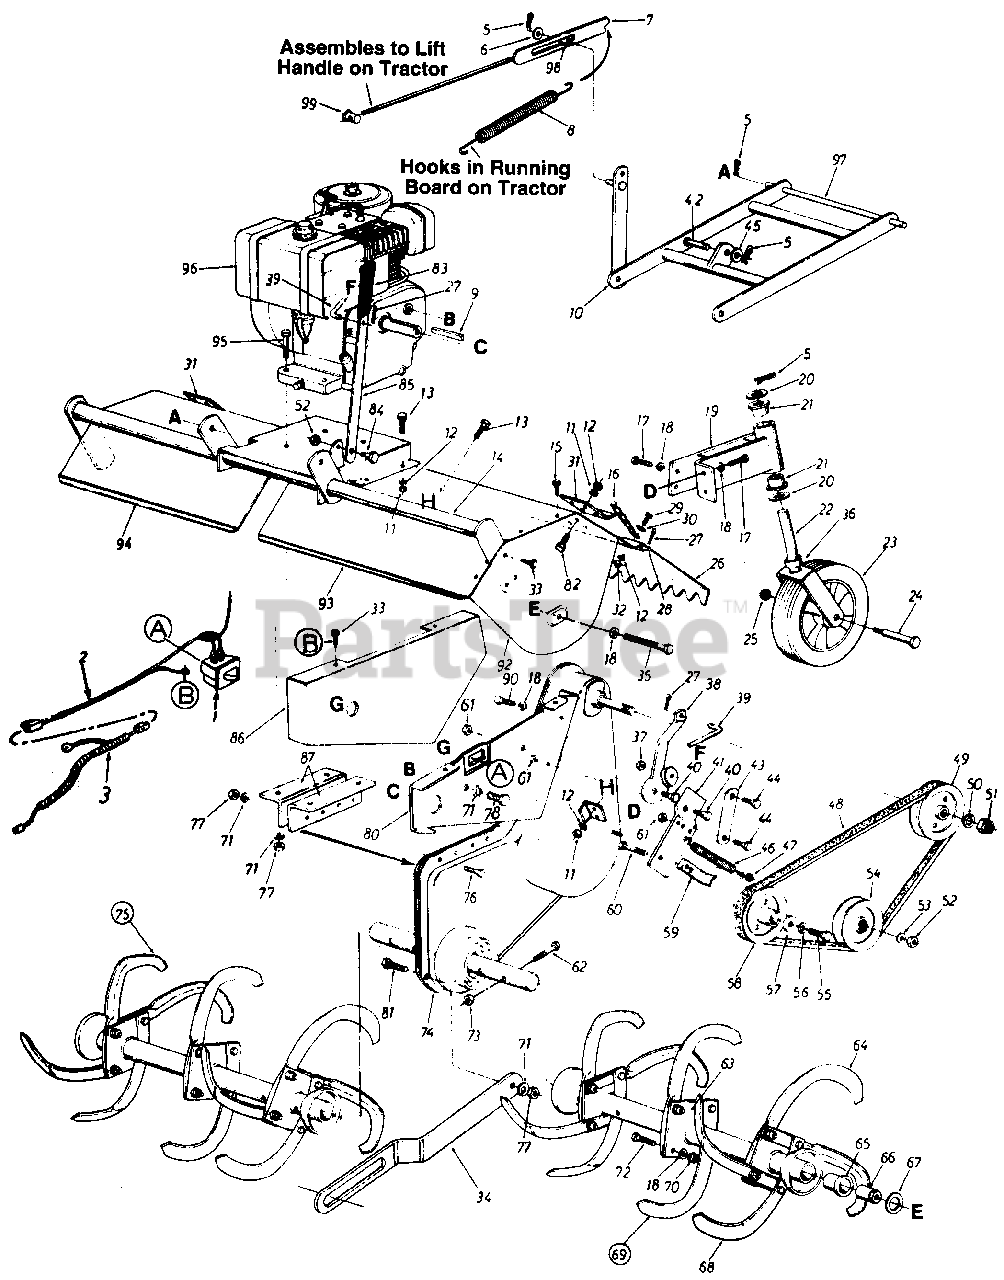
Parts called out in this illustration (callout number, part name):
1	Safety Switch
2	Wire Harness
3	Adapter Harness
5	Internal Cotter Pin
6	Fl-Wash. 1/2" I.D. x .93" O.D,
9	Sq. Key 1/4" x 1/4" x 2.00" Lg.
12	L-Wash. 1/4" I.D.
13	Hex Bolt 1/4-28 x .62" Lg.
16	#2 Dog Chain x 20" Lg.
17	Hex Wash. Hd. Self-Tap Scr. 3/8-24 x .75" Lg.
18	L-Wash. 3/8" I.D.
21	Flange Bearing 3/4" I.D. x 1.00" O.D.
24	Shoulder Bolt .623" I.D. x 3.62" Lg.
25	Hex Cent. L-Nut 7/16-14 Thd.
28	L.H. Flap Rod
29	Hex Bolt 1/4-20 x .62" Lg.
30	Fl-Wash. 1/4" I.D.
33	Hex Wash. Hd. Self-Tap Scr. 1/4" x .62" Lg.
36	Spacer .752" I.D. x 1.25" O.D.
37	Hex Cent. L-Nut 5/16-18 Thd.
40	Shoulder Bolt 7/16" Dia. x 1.75"
45	Fl-Wash..50" I.D. x 1.0" O.D. x .06
46	Extension Spring .62" O.D. x 6.12" Lg.
47	Hex Crown Nut 3/8-24 Thd.
48	"V"-Belt (Kevlar)
49	1/2" "V"-Pulley 4.75" O.D. x .625" Bore
50	L-Wash. 5/8" I.D.
51	Hex Ins. L-Nut 5/18-16 Thd.
52	Hex Cent. L-Nut 3/8-16 Thd.
53	Fl-Wash. 3/8" I.D.
54	Idler Pulley 4.0" O.D.
55	Hex Bolt
56	L-Wash. 7/16" I.D.
57	Fl-Wash. 7/16" I.D. x 1.38"
58	1/2" "V"-Pulley .475" O.D. x 1.00" Bore
61	Hex Cent. L-Nut 5/16-18 Thd.
62	Hex Bolt 7/16-14 x 2.00" Lg.
66	Spacer
67	Thrust Wash. 1/2" I.D. x 1.55"
71	L-Wash. 5/16" I.D.
72	Hex Bolt 3/8-24 x 1.5" Lg.
73	Hex Cent. L-Nut 7/16-14 Thd.
77	Hex Nut 5/16-18 Thd.
78	Hex Bolt 5/16-24 x .62"
80	Clutch Support Bracket
81	Shld. Bolt .435" Dia. x .265" 5/16-18 Thd.
82	Hex Bolt 1/4-28 x .75" Lg.
83	Plastic Grip
84	Shoulder Bolt .498" Dia. x .212" Lg.
96	8 H.P. Engine
97	Hitch Rod
98	Push Bar Sleeve .503" I.D. x .624" O.D.
99	Ferrule
